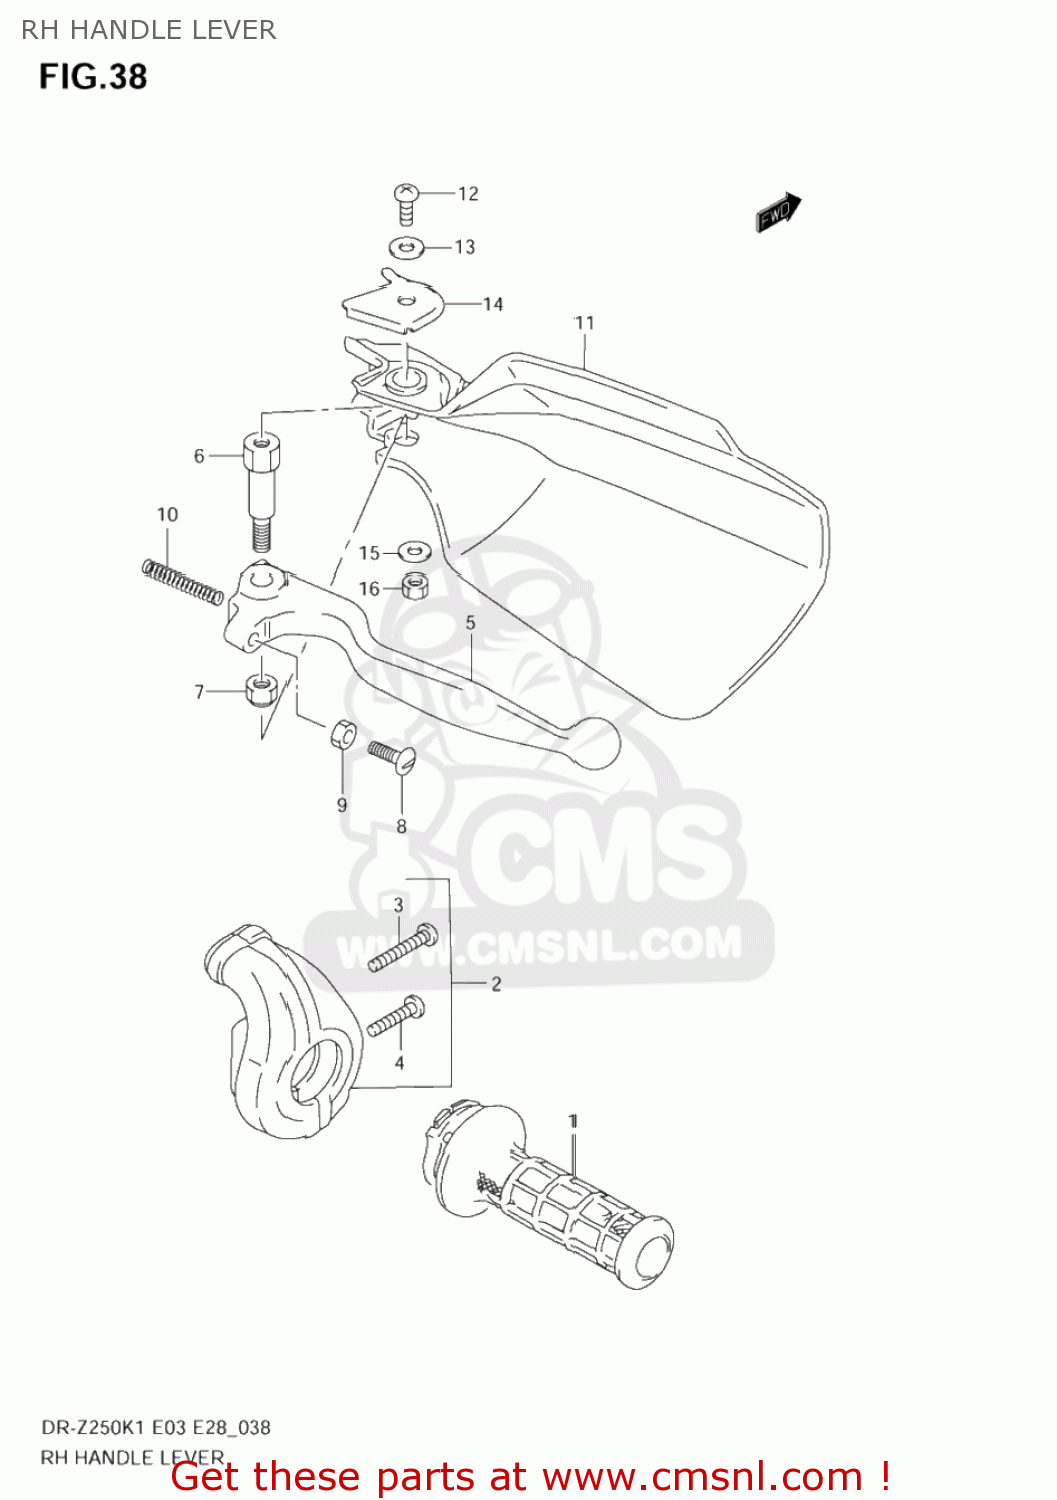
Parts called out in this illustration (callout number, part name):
1	GRIP,THROTTLE
2	CASE ASSY,THROTTLE
3	SCREW(5X25)
4	SCREW
5	LEVER,BRAKE
6	BOLT,BRAKE LEVER PIVOT
7	NUT 6MM
8	BOLT,ADJUST
9	NUT
10	SPRING,RETURN
11	COVER,KNUCKLE,RIGHT
12	SCREW
13	WASHER(5.5X16X1.2)
14	PLATE,KNUCKLE COVER,R UPR
15	WASHER(6.5X16X1.6)
16	NUT 6MM
